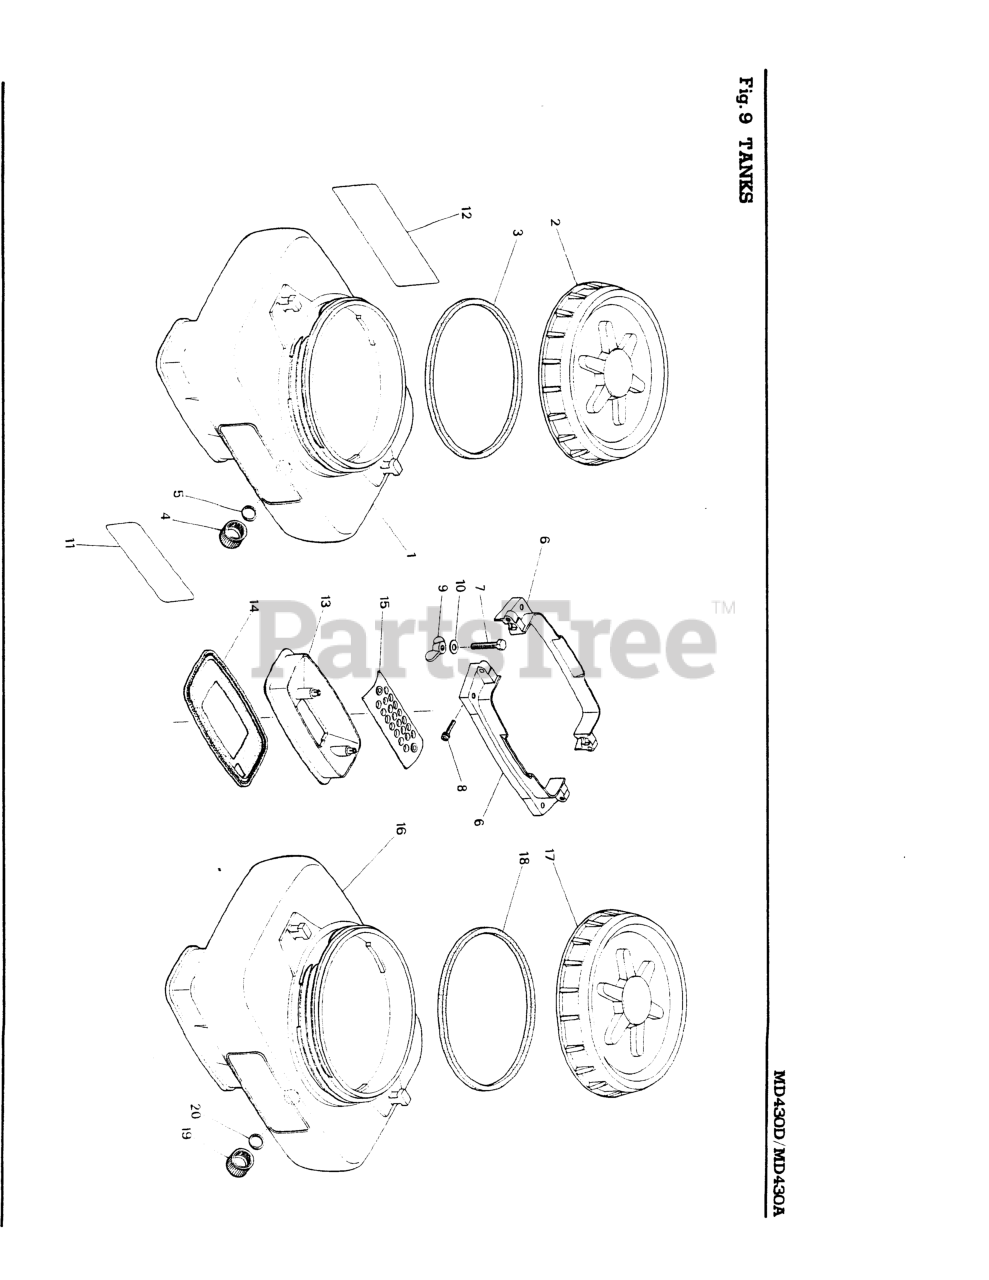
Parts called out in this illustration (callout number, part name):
1	TANK ASSY
2	CAP ASSY
8	BOLT, M6 x 25
9	NUT (NO LONGER AVAILABLE)
13	COVER (NLA)
15	PLATE (NLA)
17	CAP ASSY
19	CAP ASSY
